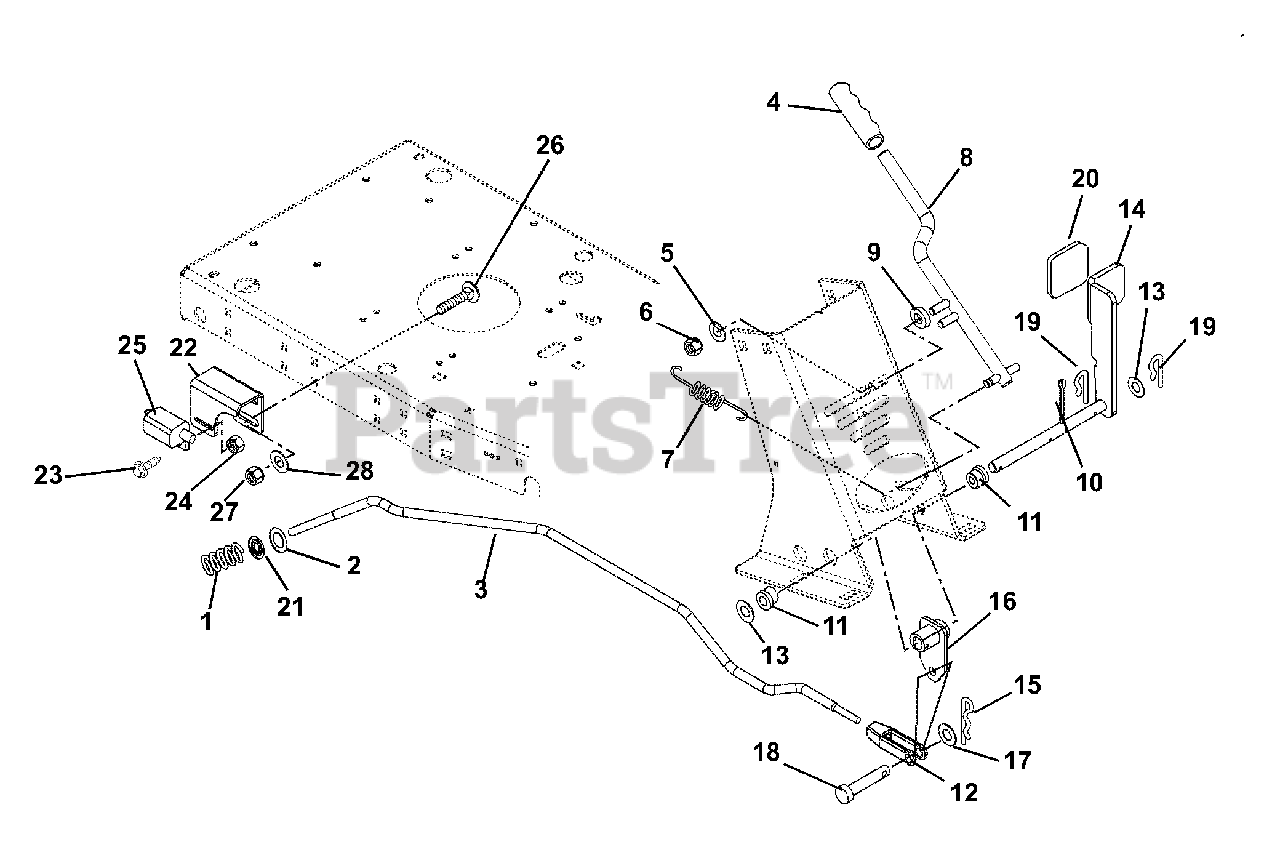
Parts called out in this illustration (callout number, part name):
1	SG-COMP .080X.52X2.90
2	WASHER, FLAT .33/2.125/.098
3	ROD, RER BRAKE
5	@WSHR-FL-STL.38X.875X.083 YWZC
6	NUT-LK-TOP-FLG .38-16 BLKZC
7	SG-TENS .048X.44X2.25 WLD 9
8	HANDLE, PARK BRAKE (WLDMNT)
9	BSHG-FLG .406X.88X.270X.140
10	@PIN-CTR .09X1.00 EXTPRSQCT YZ
11	BSHG-FLG .515X.750X.745X1.00NY
12	YOKE, .312-24 X 2.25
13	WSHR-FL-STL .505X1.00X.062YWZC
14	WLDMT-BRAKE PEDAL
15	PIN-HAIR, ENDRIES #25 YWZC
16	BRAKE ROD ARM & HUB
17	WSHR-FL-STL .328X.87X.179 YWZC
18	PIN-CLEV .312X.822 HDND PL
19	CLIP, SPRING
20	GRIP, PEDAL
21	NUT-PUSH .312
22	BRKT, SWITCH MOUNT
23	@SCR-MCH 10-24X.75 HWH YWZC
24	@NUT-LK-NYL 10-24 W/INSRT YWZC
25	SWITCH,INTERLOCK
26	BLT-RDHDSQNK .38-16X1.00 G5BZ
27	@NUT-LK-NYL .38-16 YWZC
28	@WSHR-FL-STL.406X.812X.065 YWZ
